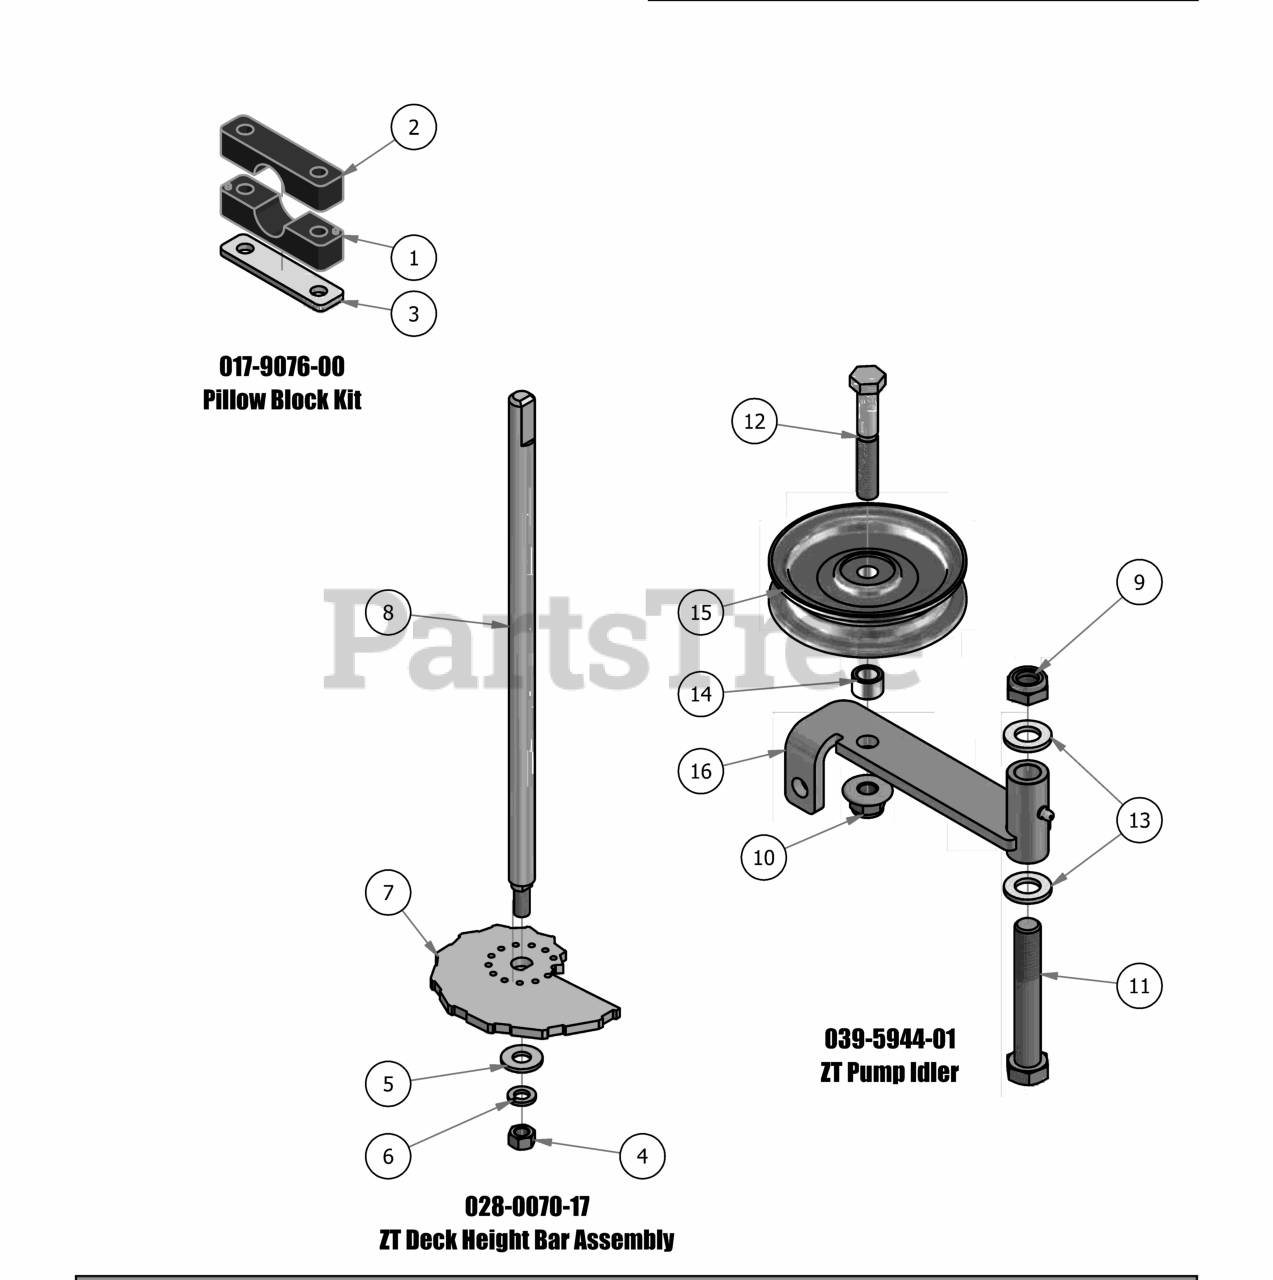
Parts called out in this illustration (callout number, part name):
1	Pillow Block MZ male
2	Pillow Block MZ female
3	Pillow Block Strap
4	3/8" Fine Threaded Jam Nut
5	3/8" Flat Washer
6	3/8" Lock Washer
7	2017 MZ/ZT Cam Plate
8	2017 Deck Height Dial Rod ZT
9	5/8" Nylock (1/2 Jam)
10	1/2-13 Nylon Flange Nut
11	5/8" x 4" Hex Bolt
12	1/2 x 2-3/4 Hex Bolt
13	.630 ID Plastic Washer
14	1/2 x 1/2 Spacer
15	4 3/4" Idler Pulley
16	Pump Idler Bracket
